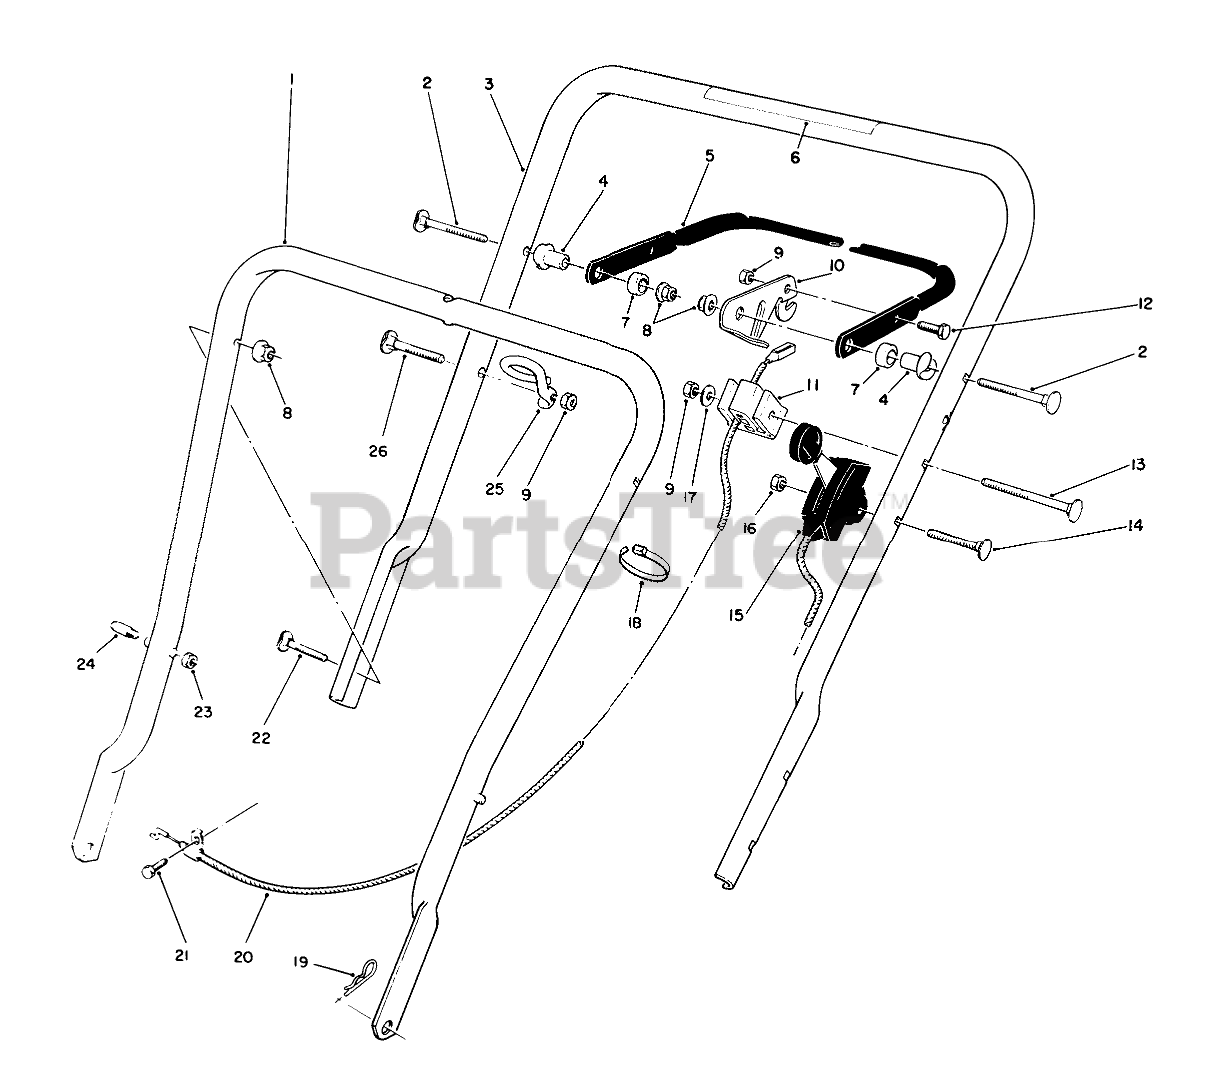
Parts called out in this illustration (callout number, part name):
1	LOWER HANDLE ASM
2	5/16-18 X 2 HNDLE SCREW
3	Handle-Upper (Incl. Ref. #6)
4	SPACER-SUPPORT
5	Bar-Control
6	DECAL - HANDLE
7	SPACER-NYLON
8	NUT-LOCK, NI
9	NUT-LOCK, NI
10	CONTROL LEVER
11	SUPPORT-CABLE
12	SCREW-HH
13	HANDLE SCREW
14	SCREW-HANDLE
15	THROTTLE CONTROL
16	NUT-LOCK, NI
17	WASHER-FLAT
18	TIE-CABLE
19	PIN-COTTER, HAIR
20	BRAKE CABLE
21	SCREW-HH
22	SCREW
23	NUT-LOCK, NI
24	HANDLE PIN
25	Guide
26	HANDLE SCREW
